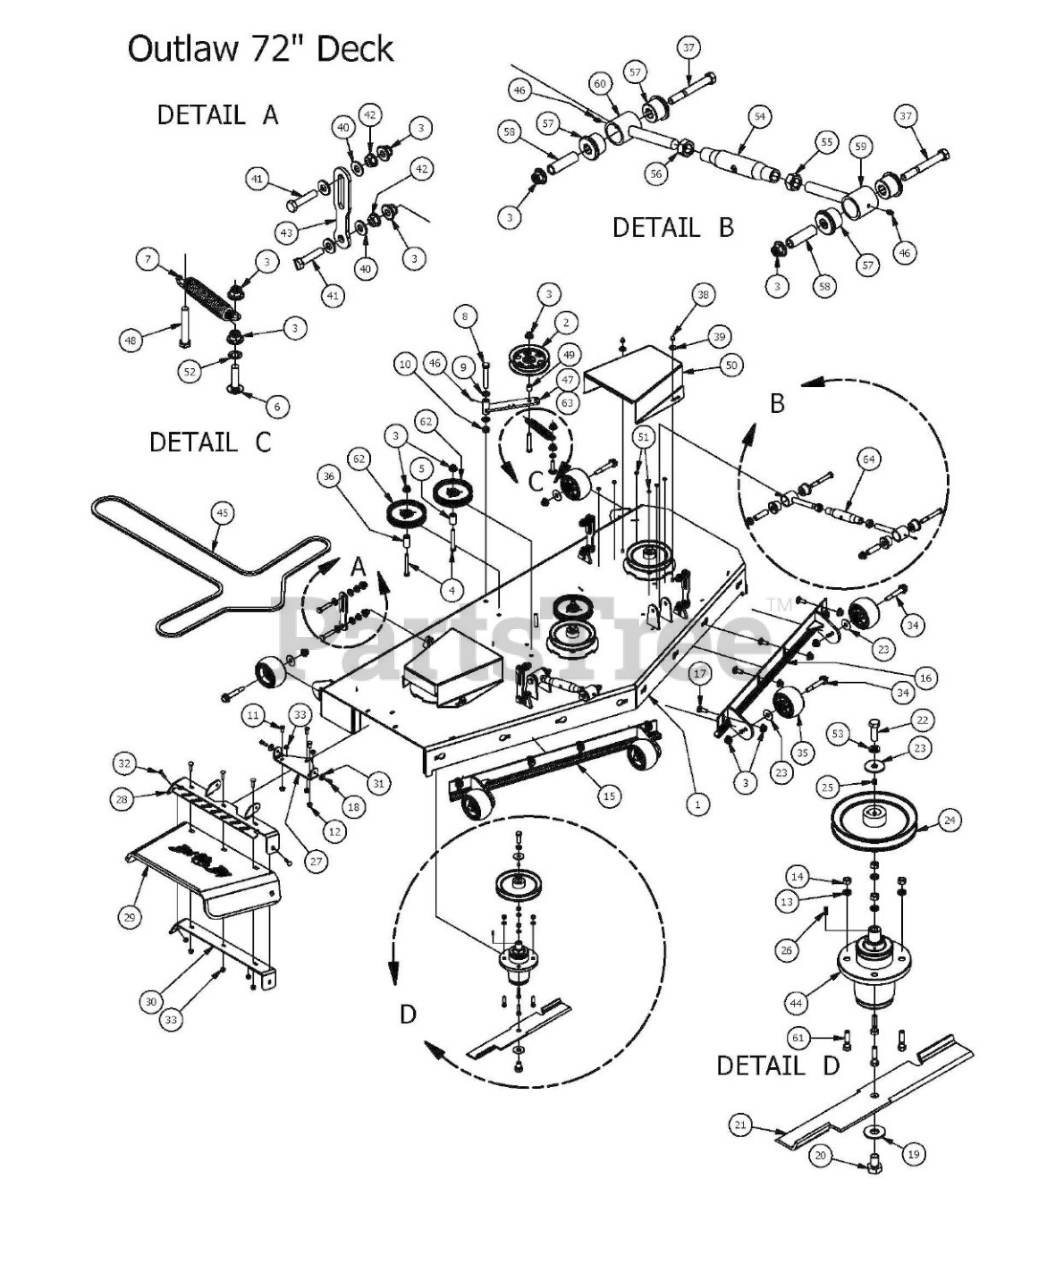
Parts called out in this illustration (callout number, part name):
1	2015 72" Deck
2	5" Idler Pully
3	1/2-13 Nylon Flange Nut
4	1/2 x 3 1/2 Flange Bolt Grade 8
5	Idler Pulley Standoff
6	1/2 x 2" Carriage Bolt
7	2015 Deck Idler Spring
8	5/8" x 4" Hex Bolt
9	.630 ID Plastic Washer
10	5/8-11 Nylon Insert Jam Half Nut
11	3/8" x 3/4" Hex Bolt
12	3/8" Flange Nut
13	3/8 Lockwasher Zinc
14	3/8-16 Hex Nuts Zinc
15	72" Deck Adustable Front (Right)
16	72" Deck Adjustable Front (Left)
17	1/2" x 1 1/4 Carriage Bolt
18	5/16" x 1" Bolt
19	5/8" Flat Washer
20	5/8" x 1 1/2" Grade 8 Hex Bolt (Fine)
21	72" High Lift Fusion Blade
22	1/2"-20 x 1 1/2 - Grade 5 Fine Thread Bolt
23	1/2" Belleville Washer
24	7" Deck Pulley
25	5/16 Set Screw
26	1/4" x 1" Key
27	Discharge Chute Hanger (deck mounted)
28	60" Discharge Chute Upper Hanger
29	Rubber Discharge Chute
30	60" Discharge Lower Bracket
31	.360 ID Plastic Washer
32	5/16" x 1 1/4" Carriage Bolt
33	5/16" Nylock Flange Nut Zinc
34	Deck Wheel Bolt
35	Anti-Scalp Roller
36	1 3/4" Pulley Spacer
37	1/2" x 4" Bolt (Grade 8)
38	Acom nut-pulley Cover
39	.360 ID Plastic Washer-Black
40	505 Nylon Spacer
41	1/2-13X 2-1/4 GR Hex Bolts
42	1/2" Flange Nut
43	Deck Hanging Tab
44	OUTLAW SPINDLE ASSEMBLY
45	B202 Belt for 72" Outlaw
46	1/4" Press in Grease Fitting
47	Deck Idler
48	1/2-13 x GR 5 Hex Bolt Zinc
49	Spacer 3/4 OD x 1/2 ID x 314 Length
50	72 Outlaw Spindle Pulley Cover
51	Black, Round Stick-On Rubber Bumper
52	.517 Square Hole Round Washer
53	1/2" Lock Washer
54	2015 Outlaw Toplink Body
55	3/4-10 Left-Handed Hex Nuts Zinc
56	3/4-10 Hex Nuts Zinc
59	Turn Left-Handed
60	Right-Handed End
61	3/8" x 1 1/2" Hex Bolt
62	5-3/4 Idler Pulley-Capitol Stampings
63	Deck Idler Assembly - Includes parts: 2,3,46,47,48,49
64	Turnbuckle Assembly
